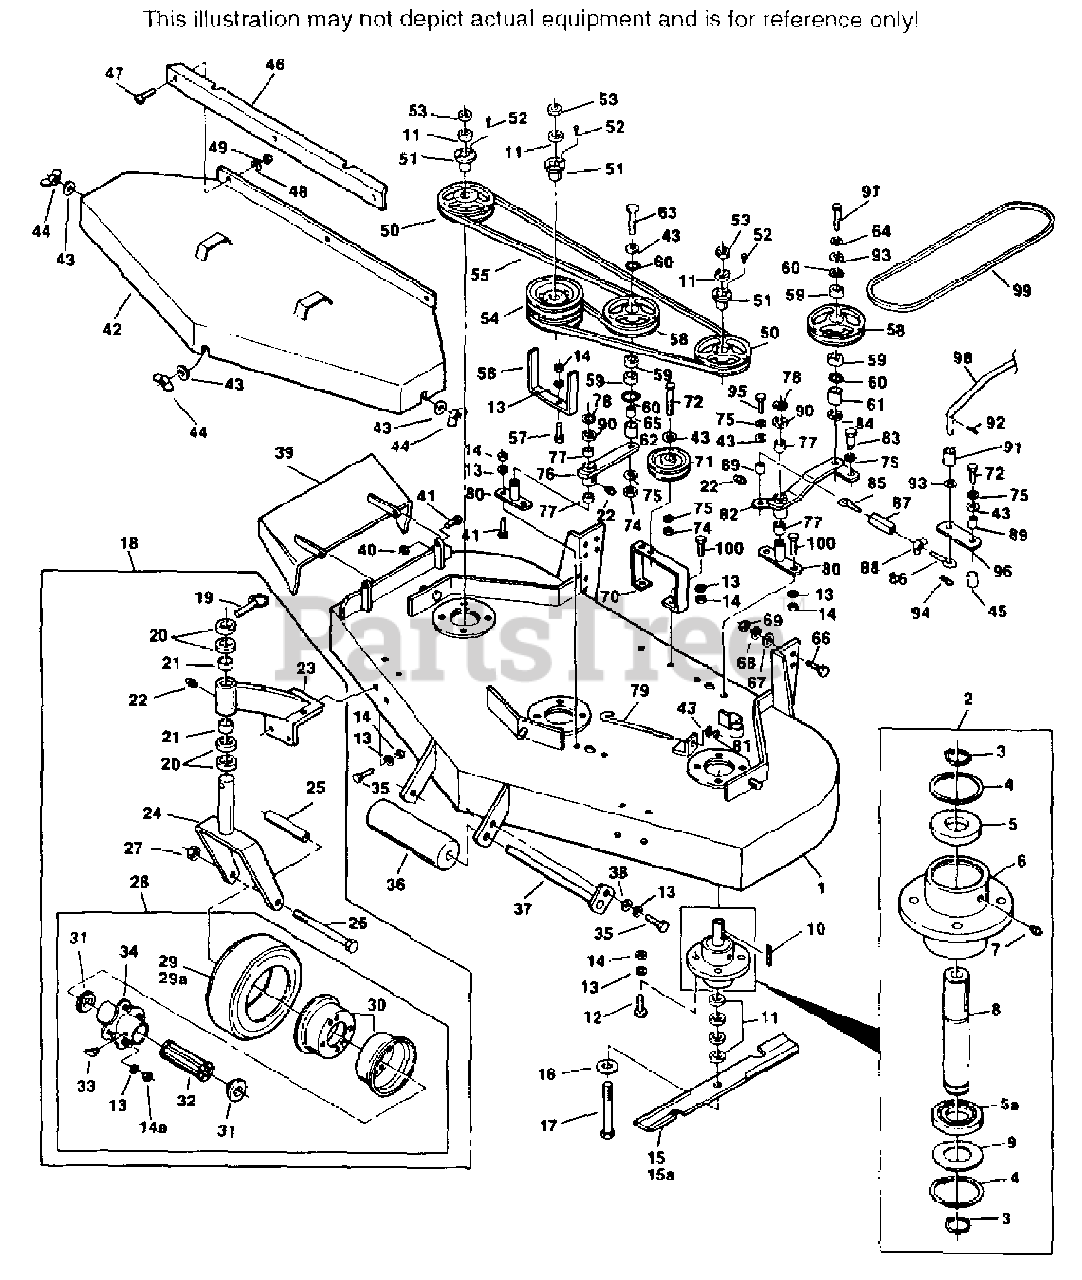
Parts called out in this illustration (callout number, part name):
1	CUTTER DECK(INCL. DECAL)
2	CUTTER SPINDLE ASSY.(INCL. 3-9)
3	RETAINING RING, 1" EXT.-INVERTED
4	RETAINING RING, 2-7/16 INT. BASIC
5	BEARING, CUTTER SPINDLE UPPER
5A	BEARING, CUTTER SPINDLE LOWER
6	SPINDLE HOUSING
7	GREASE FITTING, STR. 5/16 SERR.
8	SPINDLE, CUTTER BLADE
9	WASHER, 1-5/16 X 2-7/16 X 16 GA.
10	KEY, 1/4 X 1/4 X 2
11	SPACER, CUTTER BLADE
15	CUTTER BLADE, 21" STD.
16	FLAT WASHER, 5/8W
17	BOLT, HEX HD., 5/8-11 X 9-1/2
18	CASTER ASSY, COMP.(INCL. 19-28)
19	QUICK PIN
20	SPACER, CASTER YOKE, 1/2 LONG
21	BRONZE BEARING
22	GREASE FITTING, STR, 1/4-28
23	SUPPORT ASSY.(INCL. 21-22)
24	CASTER YOKE WLD.
25	SLEEVE, CASTER WHEEL BEARING
26	BOLT, HEX HD., 1/2-13 X 5-1/2
28	WHEEL ASSY.(INCL. 13-14, 14A, 29-34)
29	TIRE ONLY, CASTER WHEEL
29A	INNER TUBE ONLY, CASTER WHEEL
30	RIM PAIR, CASTER WHEEL
31	RETAINER, BEARING, CASTER WHEEL
32	ROLLER BEARING, CASTER WHEEL
33	GREASE FITTING, 45' 1/4-28
34	HUB ASSY. W/BOLTS
36	GUIDE ROLLER
37	ROLLER SHAFT WLD.
38	WASHER, 11/32 X 11/16 X 16 GA.
39	DISCHARGE CHUTE WLD.
40	HEX NUT, 5/16-18 ELASTIC STOP
42	BELT COVER
43	WASHER, 25/64 X 15/16 X 12 GA.
44	WING NUT, 3/8-16
45	SPACER
46	BELT COVER SKIRT
47	MACH SCRW, 1/4-20 X 1/2 TRUSS HD.
50	PULLEY(INCL. 51-52)
51	TAPER HUB
54	PULLEY, DOUBLE(INCL. 51-52)
55	BELT, BLADE DRIVE
56	BELT GUIDE
58	PULLEY IDLER
59	BEARING
60	RETAINING RING, 1-9/16 INT. BASIC
61	SLEEVE, IDLER BEARING
62	SPACER, IDLER BEARING
65	SLEEVE, IDLER PULLEY
69	HEX NUT, 1/2-13, ELASTIC STOP
70	IDLER PULLEY SUPPORT
71	PULLEY, BELT GUIDE
76	IDLER ARM ASSY.(INCL. 22 & 77)
77	BRONZE BEARING
78	RETAINING RING, 3/4 EXT.-"E"
79	ROD, IDLER PULL, J
80	IDLER PIVOT WLD.
81	HEX NUT, 3/8-16 ELASTIC STOP
82	IDLER ARM ASSY.(INCL. 22 & 77)
83	SHOULDER BOLT
84	SPACER, IDLER
85	EYEBOLT, LH
86	EYEBOLT, RH
87	TURNBUCKLE
88	WING NUT, 5/16-18
89	SLEEVE, CAM CLUTCH
90	WASHER 3/4(49/64 X 1-1/4 X 16 GA.
91	SLEEVE, CLUTCH ROD
93	WASHER, 33/64 X 1 X 16 GA.
94	HAIR PIN, LARGE
96	CAM LINK
98	ROD, BLADE ENGAGE(APPROX. 27" LONG)
99	BELT, CUTTER DRIVE
100	IDLER PIVOT WLD.
